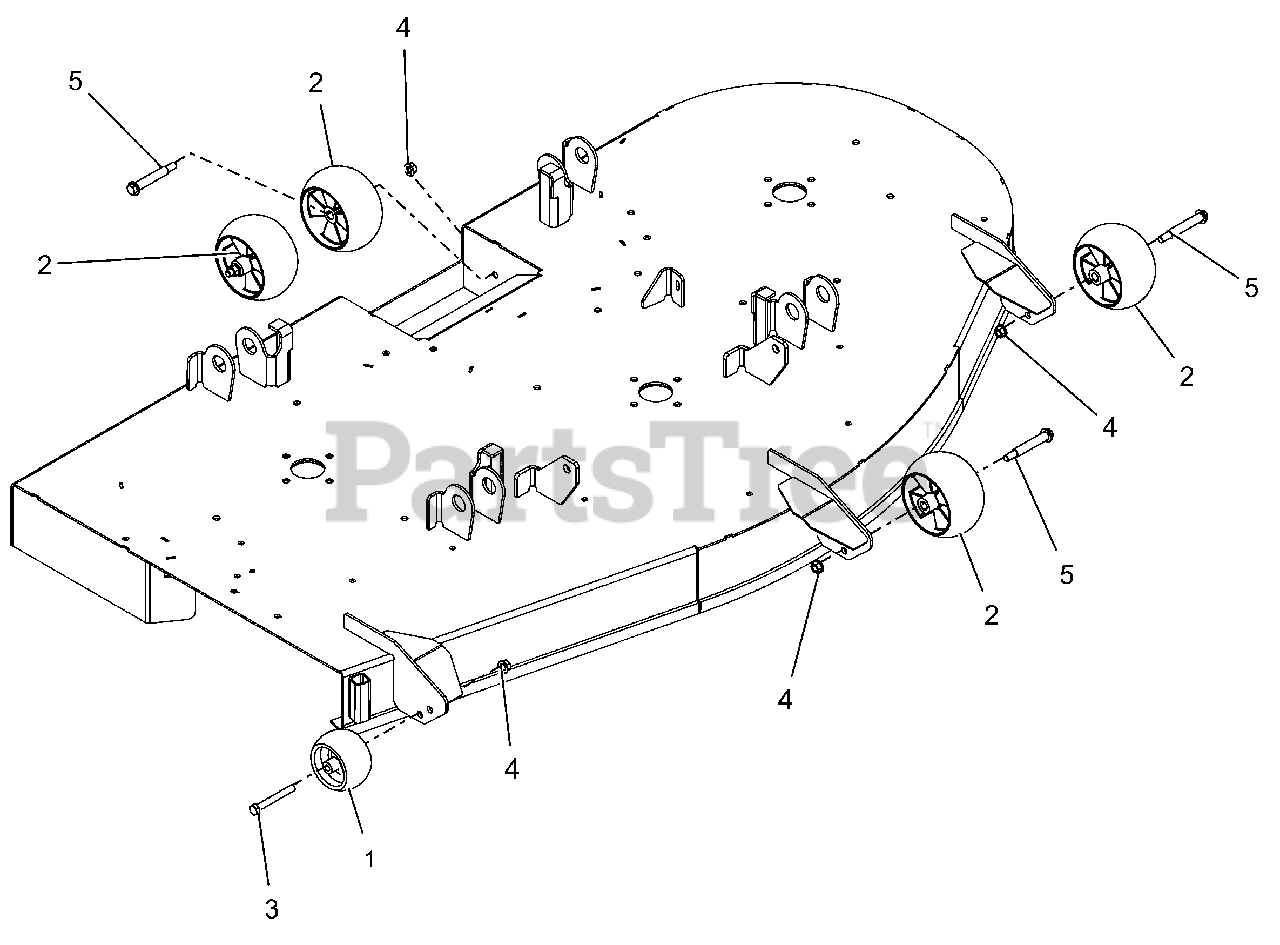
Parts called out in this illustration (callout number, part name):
2	ANTI-SCALP WHEEL - 5X OS
3	BLT-HEX .38-16X3.00 HEX 8 YWZC
4	@NUT-LK-TOP-FLG .38-16 YWZC
5	BLT-SHLDR .38-16X2.50 HWH G5
